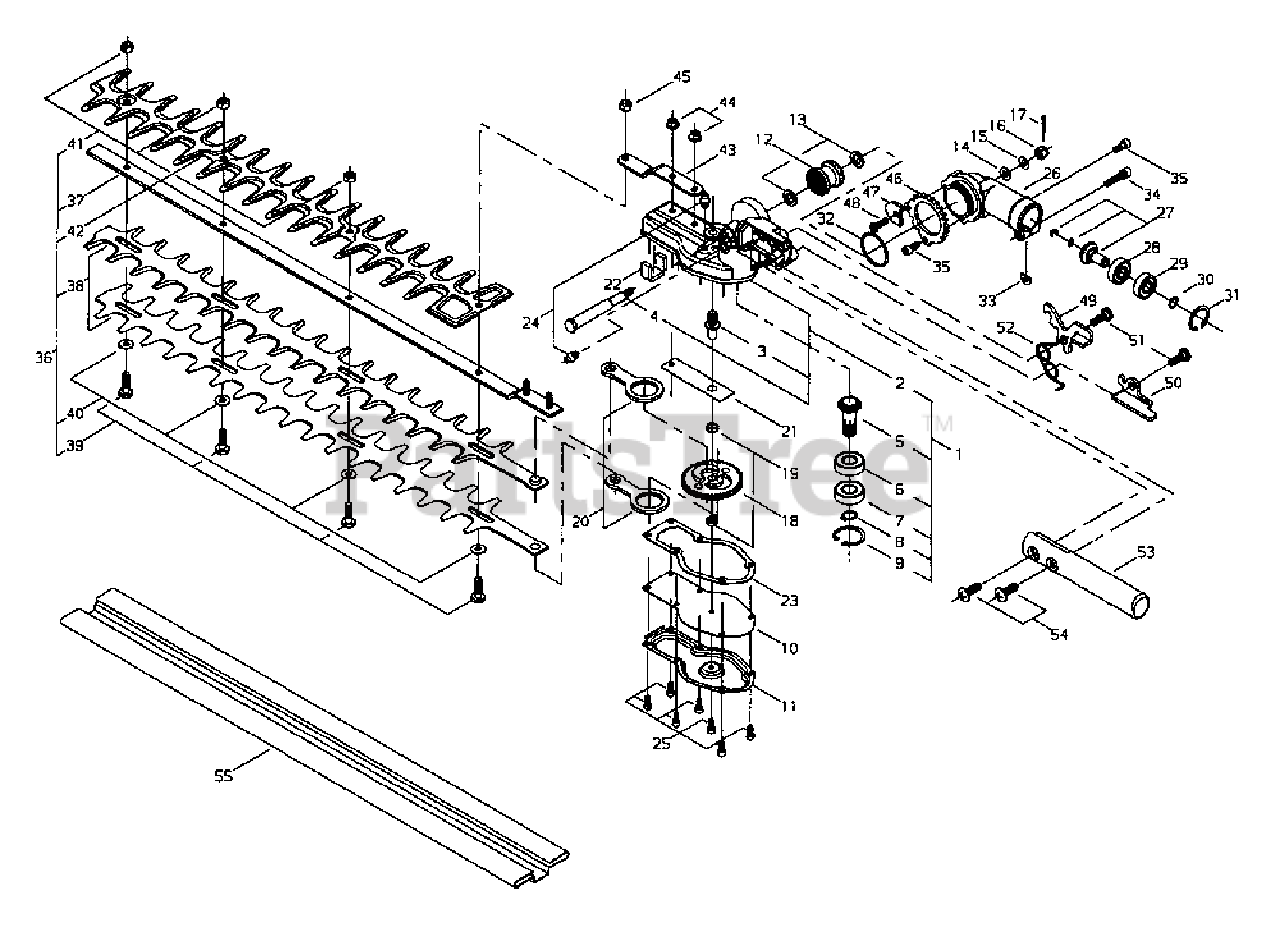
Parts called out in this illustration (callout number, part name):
1	GEAR CASE ASSY
2	CASE, GEAR - LOWER
3	PIPE, MAIN
4	SHAFT
5	GEAR - SHAFT
6	BEARING, BALL - 6001
7	BEARING, BALL - 6001ZZ
8	RING, RETAINING - 12
9	RING, RETAINING - 28
10	PLATE, GEAR CASE
11	CASE, GEAR - LOWER
12	GEAR SET - BEVEL
13	COLLAR
14	WASHER - 6
15	WASHER - CONICAL
16	NUT - CASTLE
17	PIN, SPLIT
18	CAM GEAR
19	SPACER
20	ROD, CONNECTING
21	PLATE, GUIDE
22	SEAL, FELT
23	GASKET
24	FITTING, GREASE
25	SCREW - 4X10
26	CASE, GEAR - UPPER
27	GEAR - BEVEL
28	BEARING, BALL - 609
29	BEARING, BALL - 609ZZ
30	RING, RETAINING
31	RING, RETAINING - 24
32	O-RING
33	SHIM
34	SCREW - 5X25
35	SCREW - 5X12
36	BLADE KIT - 22" (55cm)
37	GUIDE BAR - 22" (55cm)
38	BLADE KIT - 22" (55cm) CHROME
39	BOLT - 6X20
40	WASHER - 6
41	LOCKNUT - 6
42	GUARD, CUTTER BLADE
43	BRACKET, CUTTER
44	NUT - 5 -- FLANGE
45	LOCKNUT - 6
46	PLATE, ADJUST
47	STOPPER PLATE
48	SCREW
49	LEVER, LOCK
50	LEVER, LOCK
51	SCREW
52	SPRING
53	LEVER, ADJUSTMENT
54	SCREW - 6X20
55	COVER, BLADE
